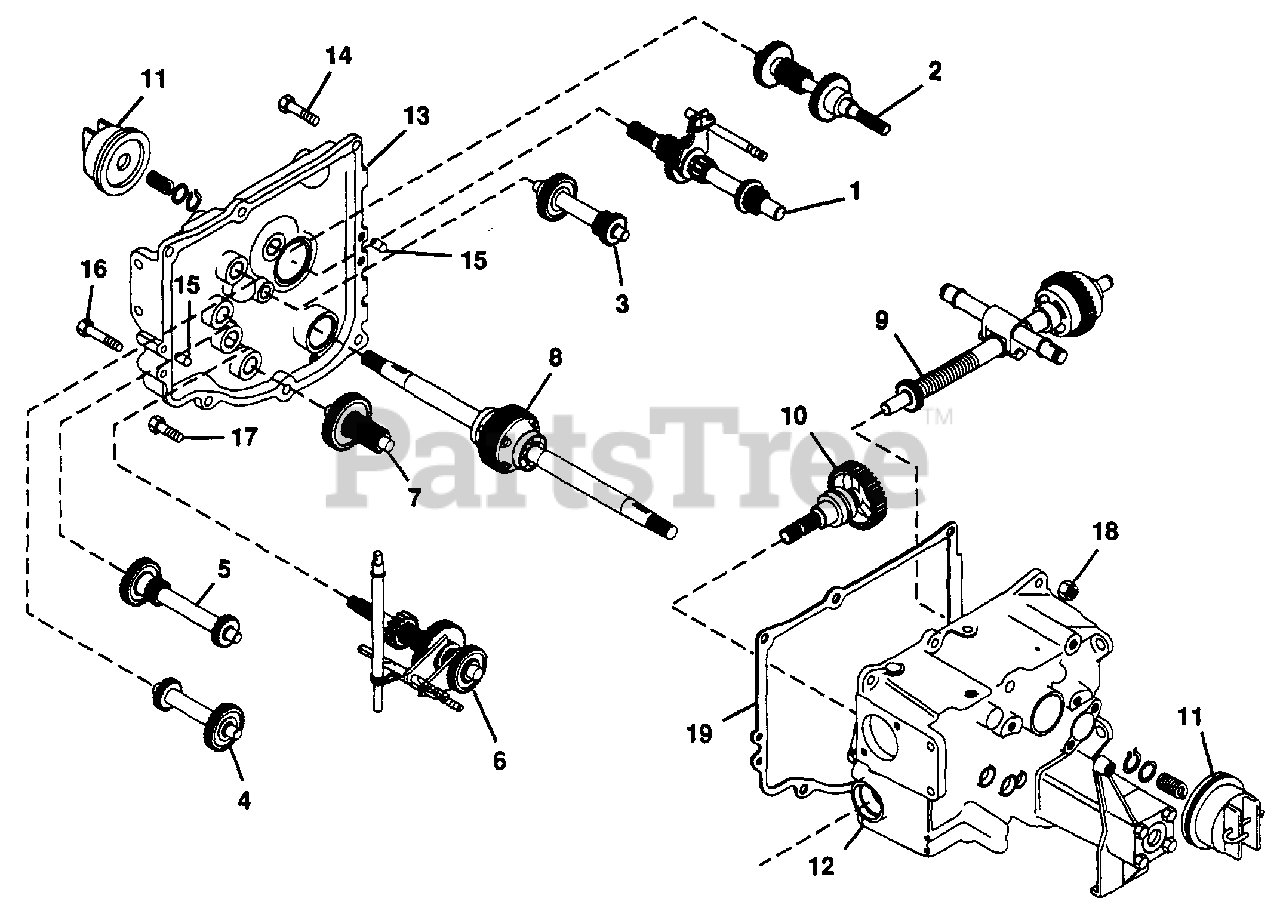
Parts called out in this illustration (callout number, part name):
1	NO. 1 SHAFT, FORWARD CLUTCH
2	NO. 2 SHAFT, REVERSE CLUTCH
3	NO. 3 SHAFT, 3RD AND 4TH GEAR
4	NO. 4 SHAFT, IDLER
5	NO. 5 SHAFT, 1ST AND 2ND GEAR
6	NO. 6 SHAFT, BRAKE-SLIDING GEAR
7	NO. 7 SHAFT, PINION-FINAL DRIVE
8	NO. 8 SHAFT, DIFFERENTIAL ASM.
9	NO. 9 SHAFT, PTO CLUTCH
10	NO. 10 SHAFT, PTO DRIVE ASM.
11	NO. 11, FWD-REV CLUTCH ASM.
12	NO. 12, TRANSMISSION CASE ASM.
13	NO. 13, TRANSMISSION COVER ASM.
14	BOLT, HEX 3/8-16X2.00
15	PIN, DOWEL .375X.625
16	BOLT, HEX 3/8-16X2.25
17	BOLT, HEX 3/8-16X1.50
18	NUT, LOCK 3/8-16
19	GASKET, TRANSMISSION COVER
